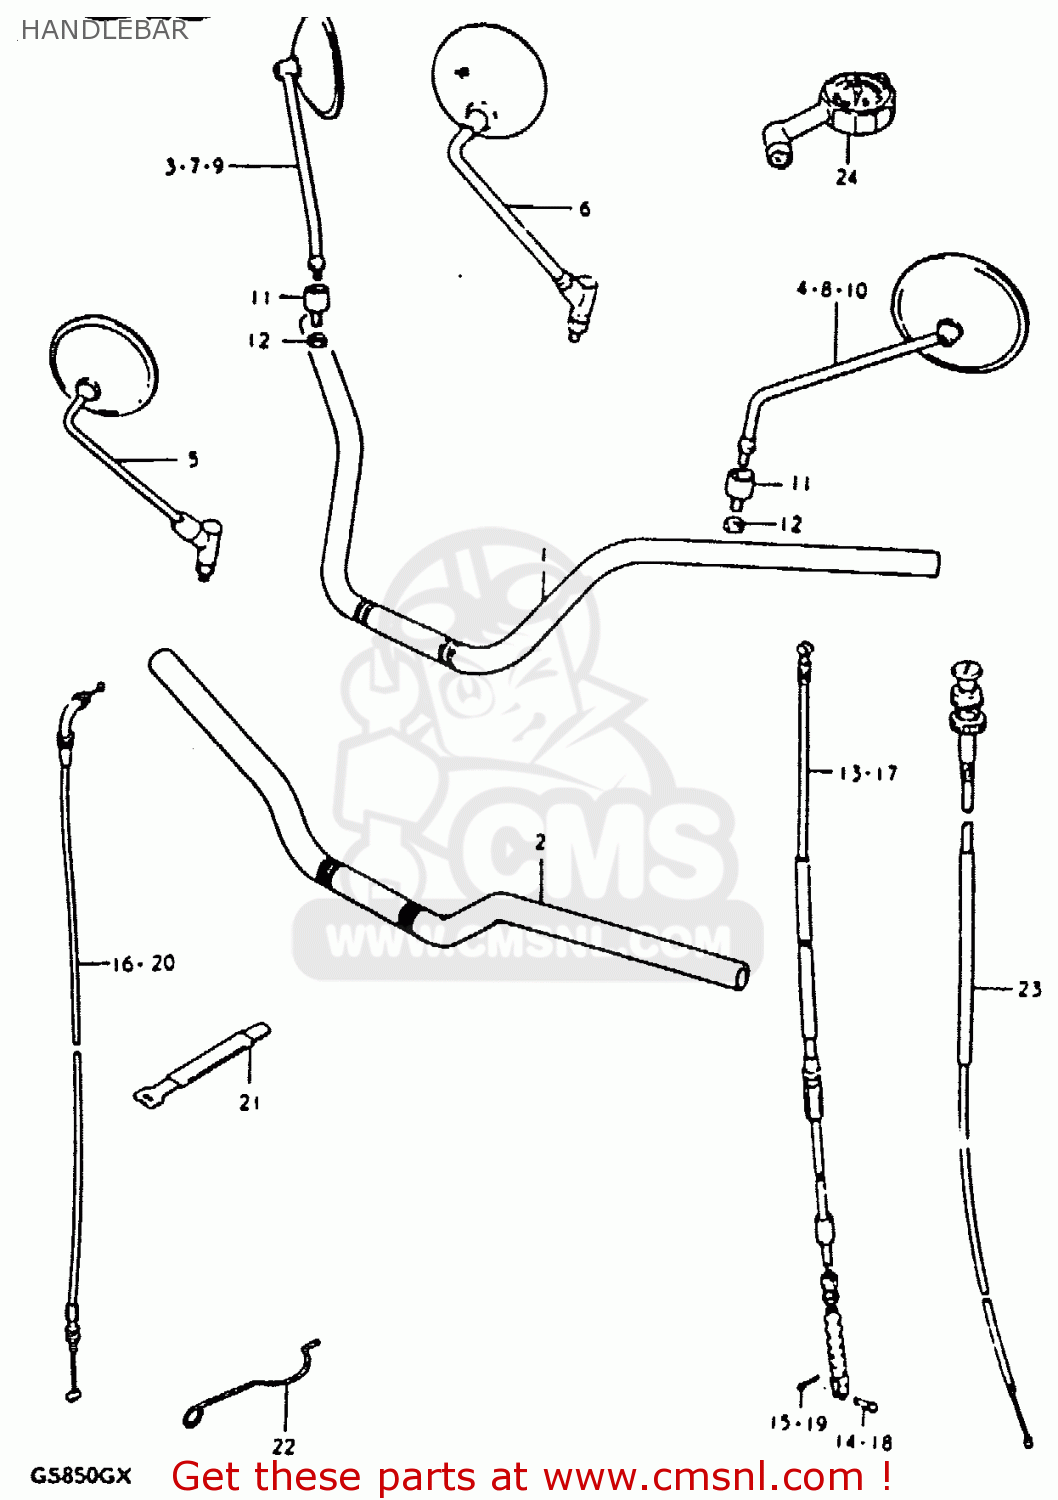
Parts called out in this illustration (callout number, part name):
1	HANDLEBAR
2	HANDLEBAR
3	MIRROR ASSEMBLY,RIGHT
4	MIRROR ASSEMBLY,LEFT
5	MIRROR ASSY,RH
11	CUSHION,REAR VIEW MIRROR
12	NUT
13	CABLE, CLUTCH (NEUTRAL)
14	PIN(L:15)
15	PIN
16	CABLE ASSEMBLY,THROTTLE
17	CABLE ASSY,CLUTCH
18	PIN(L:15)
19	PIN
20	CABLE ASSEMBLY,THROTTLE
21	CLAMP
22	GUIDE,CABLE
23	CABLE ASSEMBLY,STARTER
24	GAUGE ASSY,AIR PRESSURE
